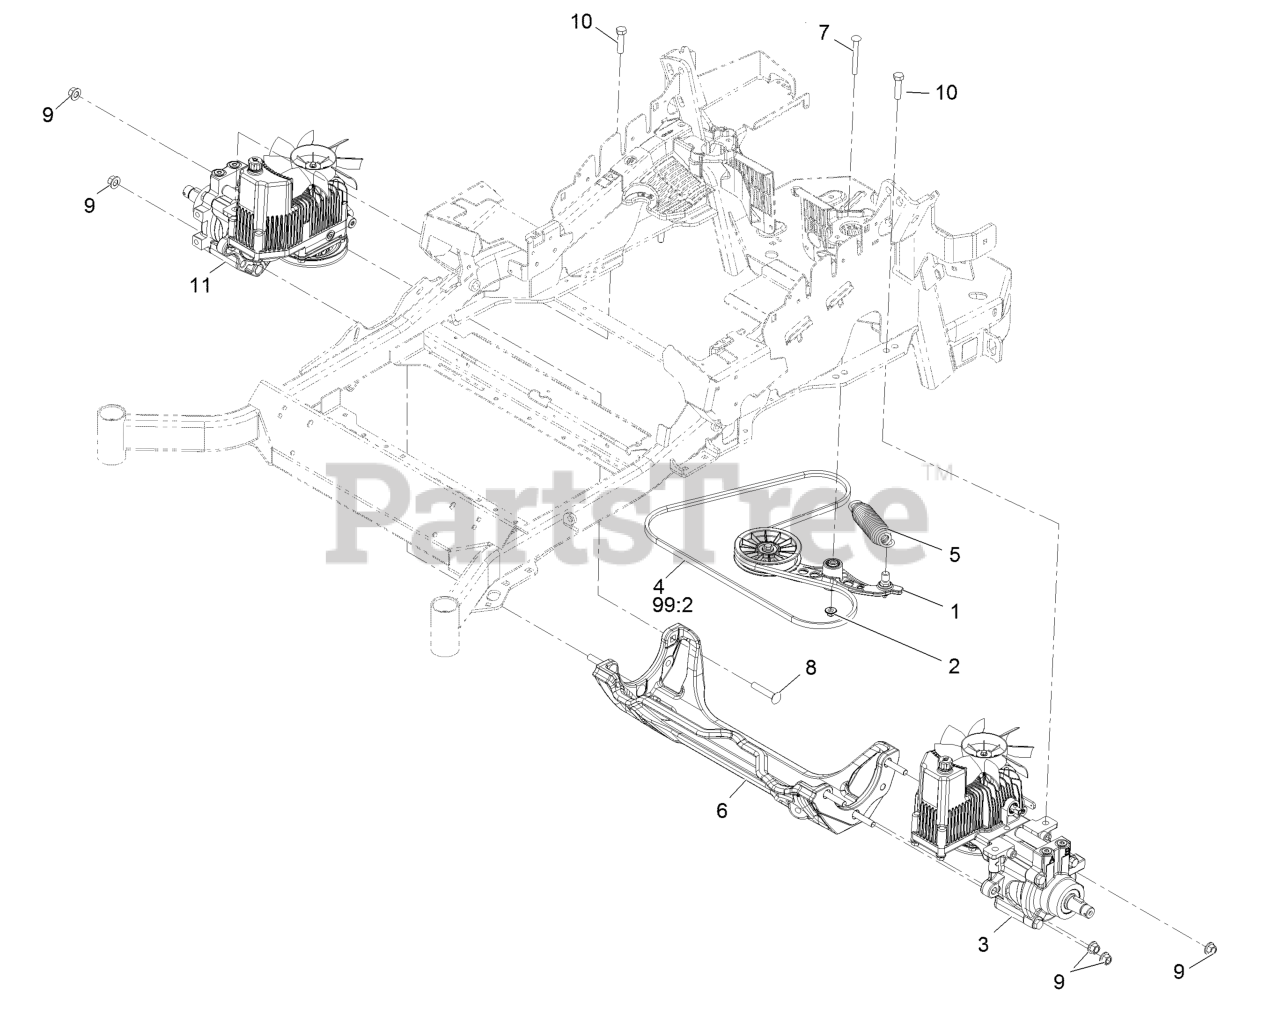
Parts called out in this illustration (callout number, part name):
1	PUMP IDLER ASM
2	Nut-Nyloc 3/8-16 Flg
3	LH HYDRO ASM (12CC NO FAN
4	BELT-V
5	SPRING-EXTENSION
6	CRADLE-HYDRO
7	BOLT-SHOULDER, CARRIAGE 3/8-16 X 3 1/2
8	SCREW-CARR
9	Nut-Lock 1/2-13
10	SCREW-HH
11	RH HYDRO ASM (12CC NO FAN
99:2	BELT-V
